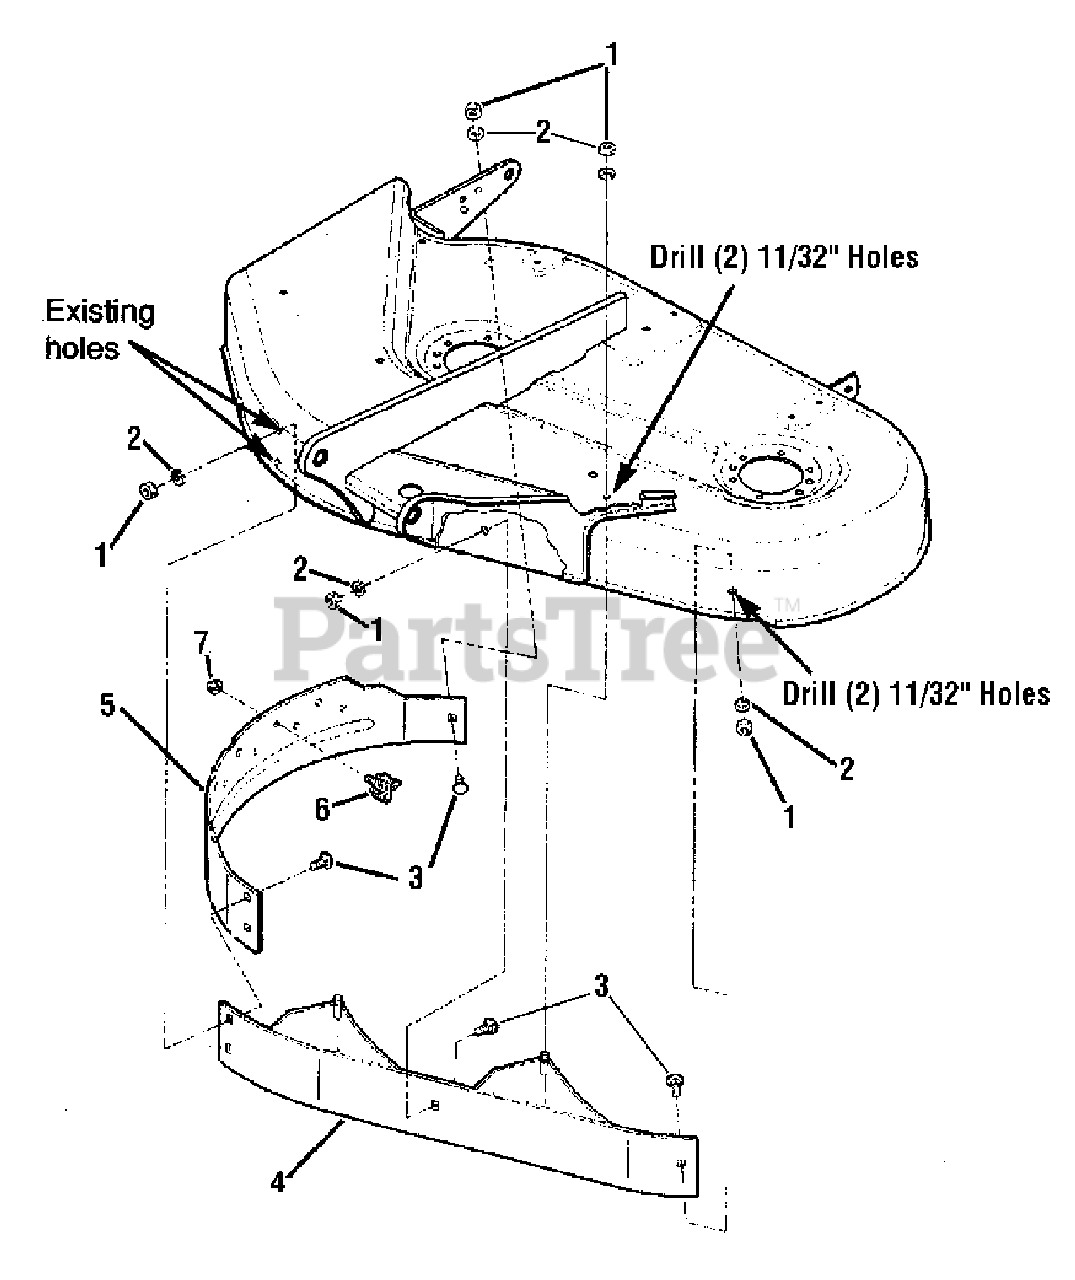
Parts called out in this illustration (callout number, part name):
1	NUT, Hex, 5/16-18
2	LOCKWASHER, 5/16
3	CARRIAGE BOLT, 5/16-18 x 3/4
4	BAFFLE & DEFLECTORS ASSEMBLY
6	LEAF SHREDDER
7	NUT, Hex Nylock, 5/16-18
